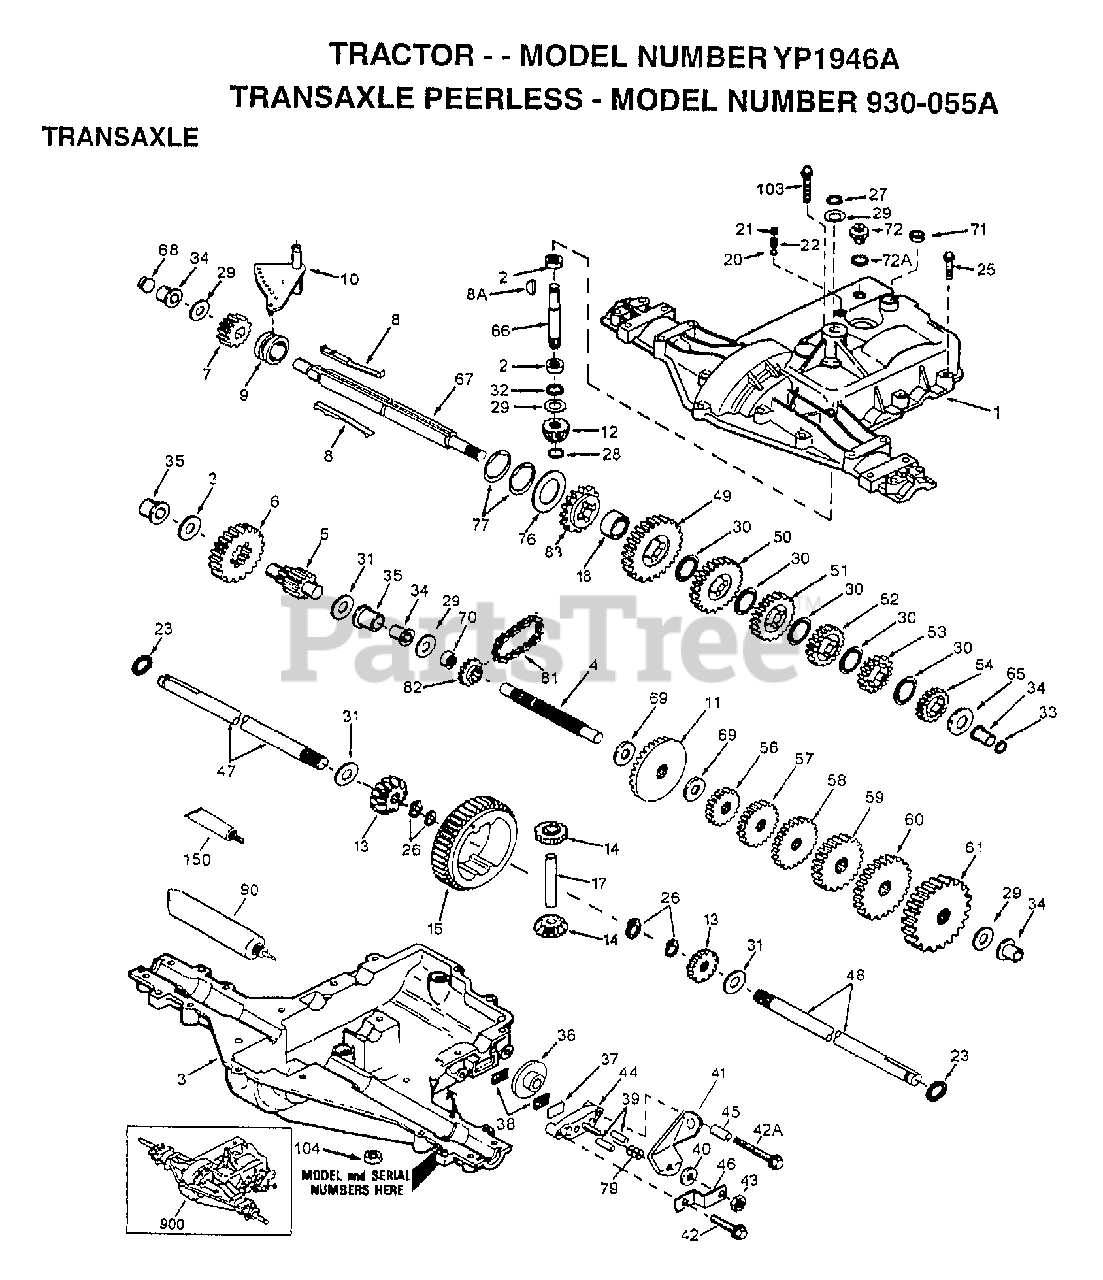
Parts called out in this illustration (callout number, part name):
1	TRANSAXLE COVER
2	BEARING, NEEDLE
3	TRANSAXLE CASE
4	SHAFT, COUNTER
5	OUTPUT SHAFT AND PINION
6	GEAR, OUTPUT
7	GEAR, SPUR, 15 TEETH
8A	KEY, WOODRUFF
9	COLLAR, SHIFTER
10	ROD & FORK ASSY, SHIFT
11	GEAR, BEVEL, 42 TEETH
12	BEVEL PINION, INPUT
13	GEAR, BEVEL
14	GEAR, BEVEL, PINION
18	SPACER, NEUTRAL
20	BALL STEEL, 5/16" DIA.
21	SCREW, 3/8-16 X 3/8"
25	SCREW, 1/4-20 X 1-1/4
26	RING RETAINER
27	RING, RETAINER
28	RETAINING RING
29	WASHER THRUST
30	WASHER THRUST
33	SEAL, SQUARE CUT
34	BUSHING, FLANGED
35	BUSHING, FLANGED
36	DISK, BRAKE
37	PLATE BRAKE PAD
41	BRAKE LEVER
42	SCREW, 1/4-20 X 1-1/4
42A	SCREW, 1/4-20 X 2-1/4
43	LOCKNUT 5/16-24
44	HOLDER BRAKE PAD
46	BRKT BRAKE LEVER
49	GEAR, SPUR, 37 TEETH
50	GEAR, SPUR, 35 TEETH
51	GEAR, SPUR, 30 TEETH
52	GEAR, SPUR, 25 TEETH
53	GEAR, SPUR, 22 TEETH
54	GEAR, SPUR, 19T
56	GEAR, SPUR, 12 TEETH
57	GEAR, SPUR, 15 TEETH
58	GEAR, SPUR, 20 TEETH
59	GEAR, SPUR, 25 TEETH
60	GEAR, SPUR, 28 TEETH
61	GEAR, SPUR, 31 TEETH
65	WASHER, THRUST
66	SHAFT, INPUT
67	SHAFT, BRAKE, 4 KEYED
69	WASHER THRUST
71	SEAL SQUARE CUT
72	THREADED PLUG 9/16-18
76	WASHER, THRUST
77	INVERTED RETAINING RING
81	CHAIN, ROLLER
82	SPROCKET 9T
83	SPROCKET 18T (REV)
90	GREASE BENTONITE, 32 OZ.
150	GASKET ELIMINATOR
900	REPLACEMENT TRANSAXLE
